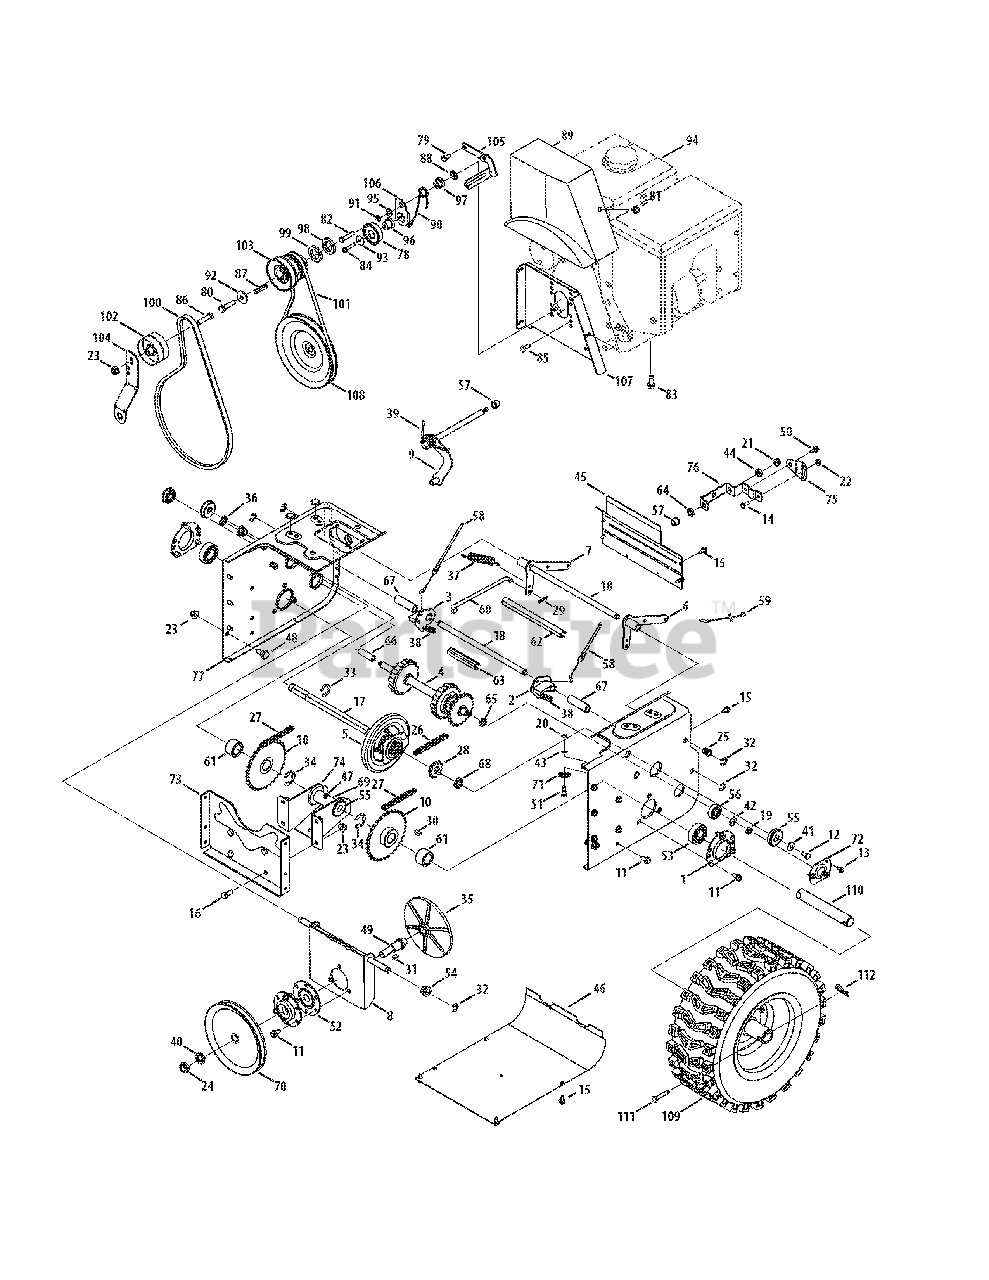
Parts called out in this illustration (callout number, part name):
1	Housing, Bearing
2	Dogg, Steering Drive, LH
3	Dogg, Steering Drive, RH
4	Shaft Assembly, Steering
5	Assembly, Friction Wheel
5	Wheel, Friction, Bonded
5	Screw, Hex Wash
6	Bracket, Auger Actuator
7	Bracket, Drive Actuator
8	Brkt, Friction Drive Suprt.
9	Rod Assembly, Shift
10	Sprocket, 32T
11	TT Screw, 5/16-18 x .750
12	Screw, Hex Cap Lock,
13	Hex Screw, 1/4-20 x .50
14	Hex Head Screw, 1/4-20
15	Screw, Hex Wash.
16	Screw, Hex Cap, 3/8-16
17	Shaft, Hex Drive
18	Shaft, Actuator
19	Nut, Hex Insert Jam Lock
20	Nut, Hex, 1/4-28 GR5
21	Flange Lock Nut, 5/16-18
22	Flange Lock Nut, 1/4-20
23	Flange Lock Nut, 3/8-16
24	Hex Nut, 5/8-18
25	Rivet Nut, 3/8-16
26	Chain, Endless, #41 x 36L
27	Chain, #420 x 40L
28	Sprocket, #41 x 10T
29	Pin, Internal Cotter
30	Key, Woodruff
31	Key, Hi-Pro, 3/16 x 5/8
32	E-Ring
33	Ring, Retaining
34	Ring, Retainer
35	Plate, Drive
36	Speed Nut, .500
37	Spring, Extension
38	Spring, Extension
39	Torsion Spring, .750 I.D. x .968 Lg.
40	Washer, Lock, 5/8
41	Wsh, Bell., .34 x .872 x .06
42	Wash, .375 x .812 x .060
43	Washer, Lock, 1/4
44	Flat Washer, .469 x .875 x .105
45	Cover, Upper Frame
46	Cover, Lower Frame
47	Fitting, Lube, 3/16 Drive
48	Screw, Shldr., .498 x .34
49	Spindle, Drive Plate
50	Shoulder Screw, .368 x .113, 1/4-20
51	Screw, Hex Shldr., 1/4-28
52	Ass’y, Bearing/Housing
53	Bearing, Self Aligning
54	Bearing, Hex Flange
55	Bearing, Ball
56	Bush, Flg, .5625 x 1.375 x .4375
57	Bush, Flg, .5 ID x .627 OD
58	Steering Cable, 35.97" Long
59	Cable, Auger Idler
60	Rod, Drive Clutch
61	Spcr., 1.0 ID x 1.50 OD
62	Spcr., .51 ID x 7.895 Lg.
63	Spcr., .51 ID x 3.66 Lg.
64	Spcr., .5151 ID x .750 OD x .220
65	Spcr., .566 ID x .87 OD x .190
66	Spcr., .566 ID x .87 OD x 1.25
67	Spcr., .514 x .632 x 2.44
68	Spacer, .675 x 1.0 x .23
69	Spcr, .6725 x 1.125 x 2.48
70	Pulley, Auger
71	Roller, Cable
72	Bearing Retaining Bracket
73	Bracket, Frame Support
74	Bracket, Axle Support
75	Speed Selector Pivot Bracket
76	Speed Selector Shift Bracket
77	Transmission Frame
78	Idler Pulley Assembly
79	Screw, Hex Cap, 5/16-24
80	Hex Hd. Screw, 3/8-24 x 1.25 GR8
81	Screw, Hx Wash Hd Tapp
82	Screw, Hex Cap, 5/16-24 x 1.50
83	Screw, 3/8-16 x 1.00
84	Screw, 1/4-20 x 1.25
85	Hex Head Screw, 5/16-24 x .875
86	Hex Head Screw, 3/8-16 x 1.75
87	Square Key, 3/16 x 1.00
88	Nut, Push
89	Cover, Belt
90	Torsion Spring, .850 dia. x .333 lg.
91	Washer, Lock, 5/16
92	Washer, Flat, .45 x 1.5 x .172
93	Washer, Flat, .265 x 1.0 x .030
94	Engine
95	Shoulder Spacer, .3175 x .500 x .094
96	Shoulder Spacer, .260 x .785 x .538
97	Shoulder Spacer, .340 x 1.00
98	Spacer, 1.155 ID x 1.78 OD x .150
99	Spacer, 1.004 ID x 1.625 OD x .50
100	V-Belt, 4L x 44.60 Lg.
101	V Belt, 3/8 x 36.68
102	Pulley, Flat Idler, 2.75 OD
103	Double Pulley, 3.25 x 2.75
104	Bracket, Auger Idler
105	Belt Keeper Bracket
106	Idler Drive Wheel Bracket
107	Belt Cover Bracket
108	Pulley, Drive
109	Wheel Ass’y. - LH
109	Wheel Ass’y. - RH
109	Valve
109	Bearing
110	Axle, Wheel, 33"
111	Pin, Clevis
112	Pin, Internal Cotter
